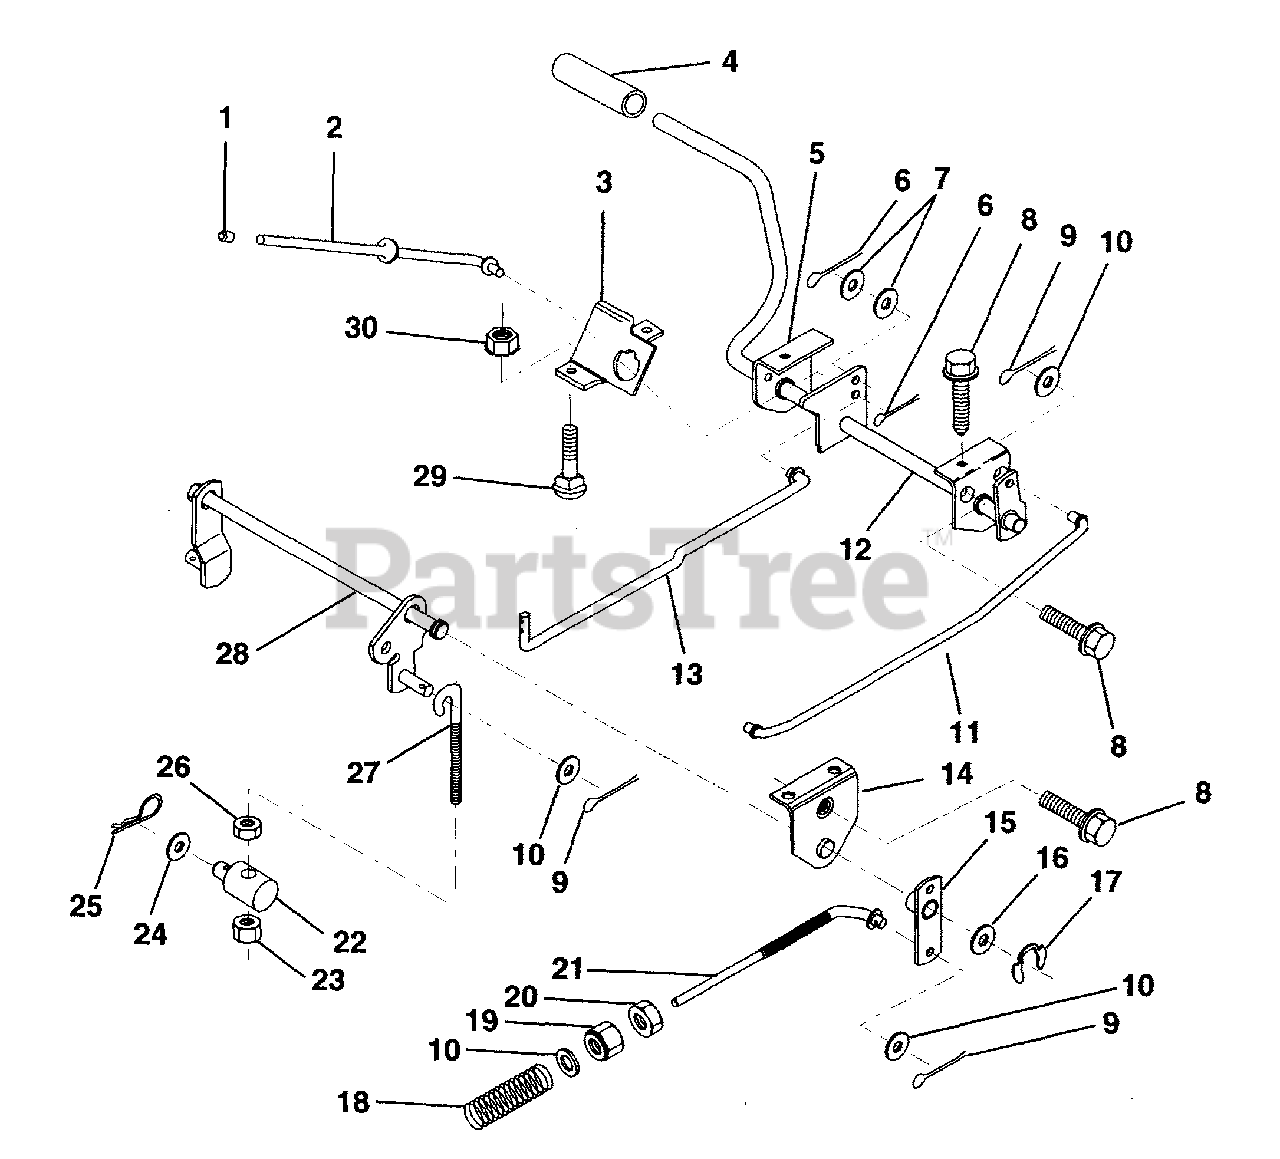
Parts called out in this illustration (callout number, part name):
1	Cap, Plunger
2	Rod, Parking Brake
3	Bracket, Parking Brake
4	Cover, Pedal
5	Bracket, Clutch/Brake Pedal, L.H.
6	Pin, Cotter 3/32 x 3/4
7	Washer 13/32 x 5/8 x 16 Gauge
8	Screw, Hex Head, Thd., Roll. 5/16-18 x 1/2
9	Pin, Cotter 1/8 x 3/4
10	Washer 13/32 x 13/16 x 16 Ga.
11	Rod, Brake Front
12	Assembly, Clutch/Brake Pedal
13	Rod, Clutch
14	Bracket, Lift, Shaft
15	Assembly, Brake, Pivot, Arm
16	Washer 25/32 x 1-1/8 x 16 Ga.
17	Ring, Klip
18	Spring, Brake Rod
19	Locknut, Hex, with Washer Insert 3/8-16 UNC
20	Nut, Hex, Jam 3/8-16 UNC
21	Rod, Rear, Brake
22	Trunnion, Lift
23	Nut, Crownlock 3/8-16 UNC
24	Washer 13/32 x 1-1/4 x 12 Ga.
25	spring Retainer
26	Nut, enterlock 3/8-16 UNC
27	Link, Threaded
28	Assembly, Rear Mower Lift
29	Bolt, Carriage 5/16-18 UNC x 3/4
30	Nut, Hex, Keps 5/16-16 UNC
